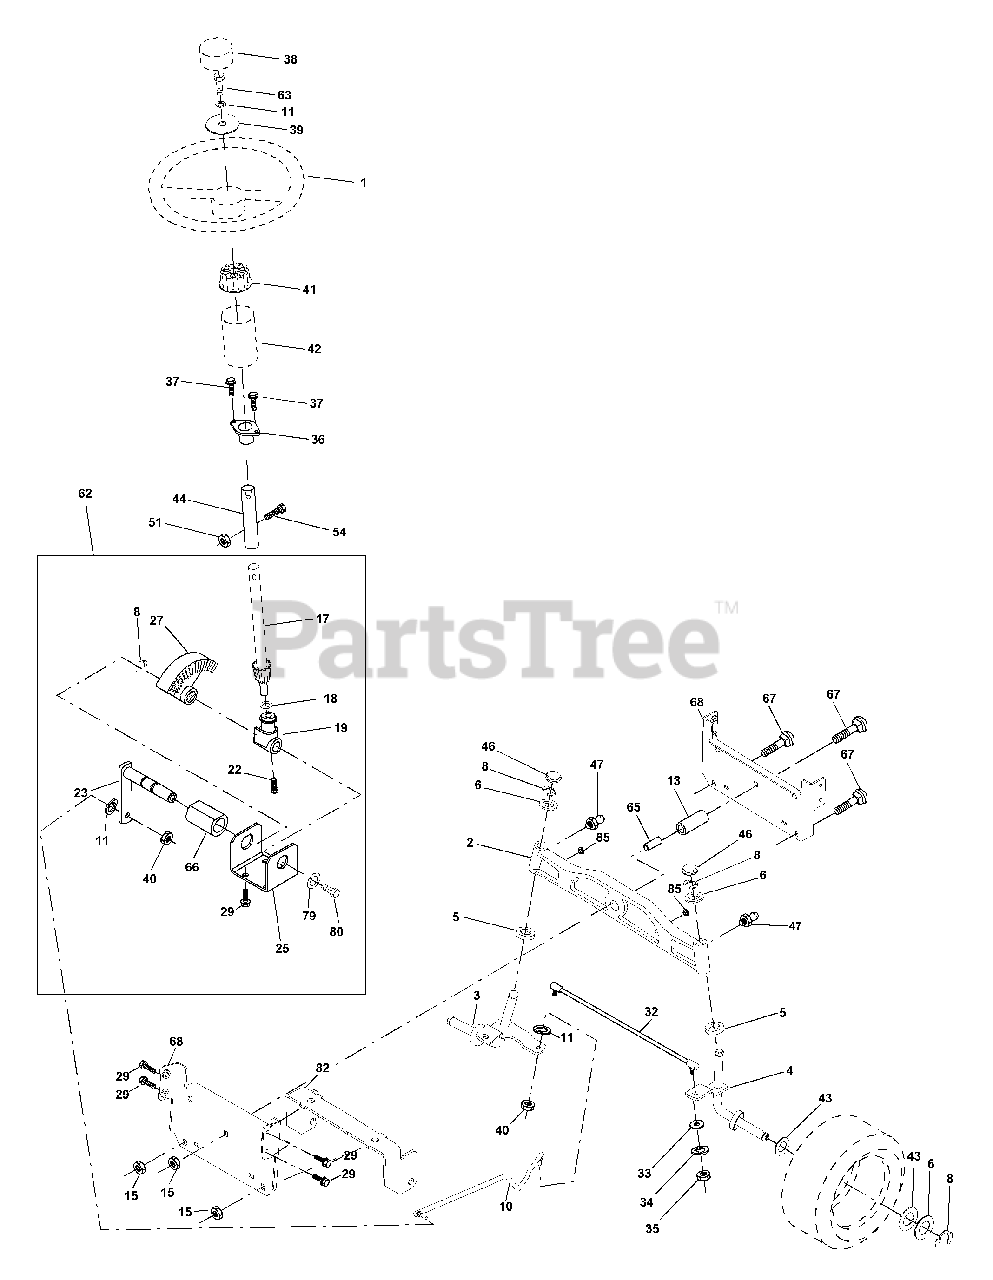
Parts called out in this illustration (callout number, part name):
1	Wheel Steering
2	Axle Asm Cast Iron LT
3	Spindle Asm LH
4	Spindle Asm RH
5	Bearing Race Thrust Harden
6	Washer 25/32 X 1-5/8 X 16 Ga
8	Ring Klip #t5304-75
10	Link Drag
11	Washer Lock Hvy Hlcl Spr 3/8
13	Spacer Brg Axle Front
15	Nut Hex Flange Lock
17	Shaft Asm Strg
18	Washer Thrust 515x 750x 033
19	Support Shaft
22	Screw Hex Wsh Hd Torx
23	Shaft Asm Pittman
25	Bracket Steering
27	Gear Sector
29	Screw 3/8-16 x .75
32	Rod Tie
33	Washer 11/32 x 3/4 x 16 Ga
34	Washer Lock Hvy Hlcl Spr 5/16
35	Crownlock Nut 5/16-24 Unf
36	Bushing Strg
37	Screw
38	Insert Cap Strg Wh
39	Washer 13/32 X 1-1/2 X 11 Ga
40	Lock nut
41	Adaptor Wheel Strg
42	Boot Steering Dash
43	Washer 25/32 X 1 1/4 X 16 Ga
44	Extension Steering Shaft LR/LT
46	Cap Spindle Fr Top Blk
47	Fitting Grease
51	Nut Lock Hex w/Ins 5/16-18
54	Bolt Fin Hex 5/16-18 Unc x 1-1/4
62	Kit, Steering Assembly Svc
63	Bolt Fin Hex 3/8-16unc x 1 Gr. 5
65	Spacer Brace Axle
66	Bearing Arm Pittman
67	Bolt Rdhd Sq 3/8-16 Unc x 2-3/4
68	Axle, Brace
79	Washer 13/32 x 1-1/4 x 12 Ga.
80	Bolt Hex Nylon 3/8-16 x 3/4
82	Bracket Susp Chassis Front
85	Fastner Christmas Tree
